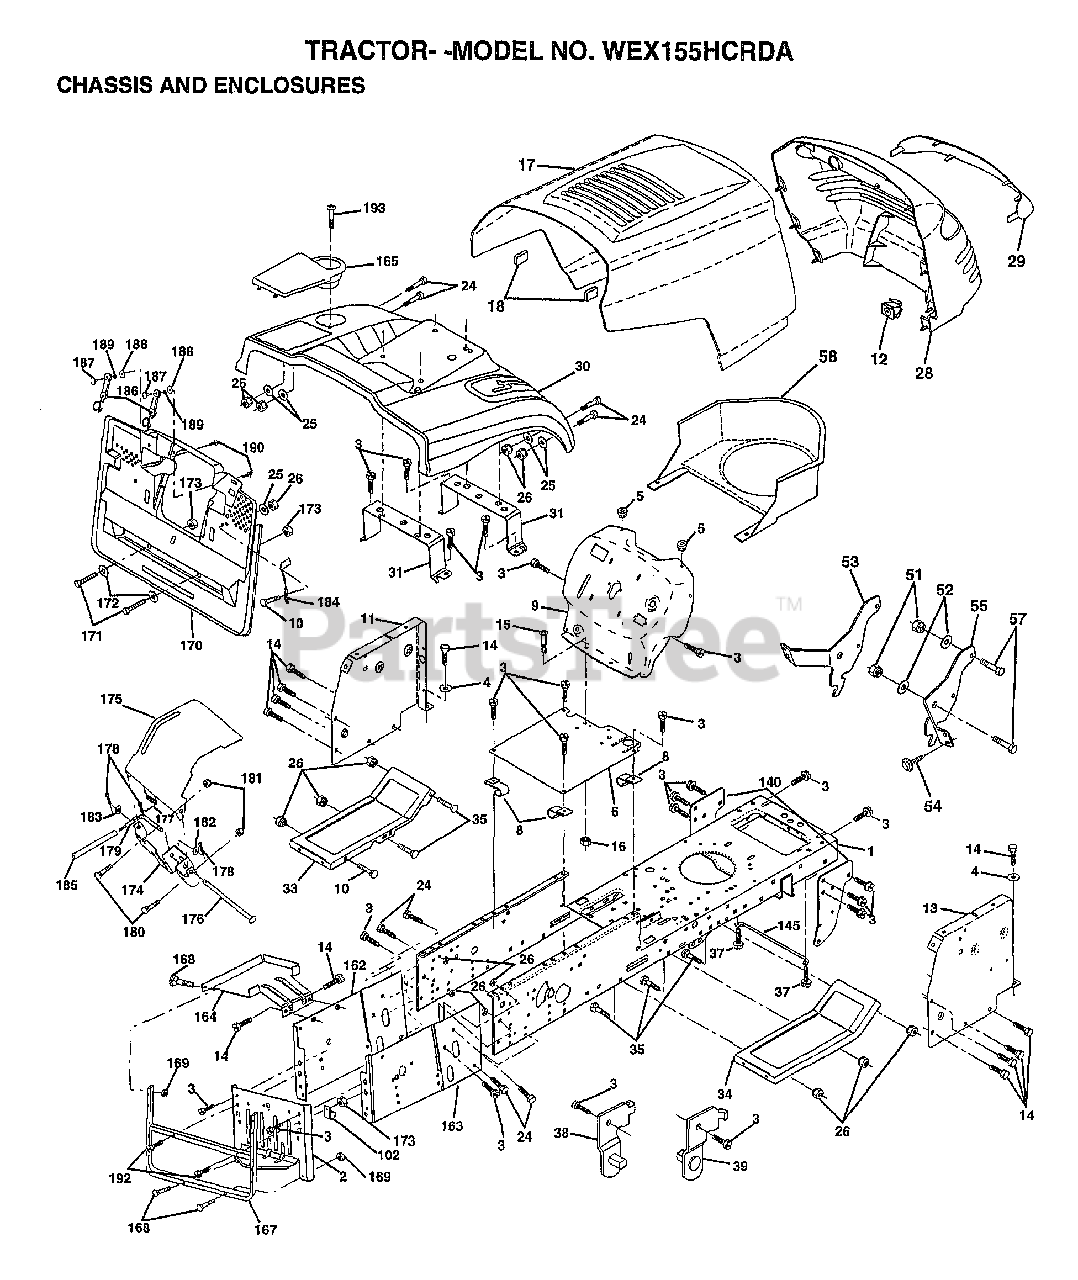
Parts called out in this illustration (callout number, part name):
1	CHASSIS.STAMPING
2	DRAWBAR.CRD
3	SCREW
4	WASHER
5	BUMPER-HOOD/DASH
6	SADDLE
8	"CLIP,INSULATOR"
9	DASH.SILKSCREEN
11	"PANEL-DASH,LH"
12	CLIP.TINNERMAN
14	SCREW LT
15	SCREW
17	HOOD.STEEL.ASSY
24	BOLT
25	WASHER
26	NUT
28	GRILLE-MS428
29	LENS.GRILLE.PRIVATE LABEL
30	FENDER.CRD.GREEN
31	BRKT.SUPT.FENDER.CRD
33	FOOTREST.LH.LT/GT
34	FOOTREST.RH.LT/GT
35	BOLT
37	SCREW LT
38	BRACKET ASM LH
39	BRACKET ASM RH
51	NUT
52	WASHER
53	BRACKET.GRILLE.LH
54	SCREW.HEX.WS.HD
55	BRACKET.GRILLE.RH
58	AIR DUCT
102	CLIP T
140	BRKT SUSPENSION
145	"ROD POVOT,CHASSIS"
148	SCREW
162	BRKT.EXT.CHASSIS.LH.CRD
163	BRKT.EXT.CHASSIS.RH.CRD
164	SUPPORT.BATTERY.CRD
165	COVER.BATTERY.CRD.BLACK.LT
167	SUPT.ASM.BACKPLATE
168	BOLT-RD HD SQ NK
170	COVER.BACKPLATE.BLACK
171	BOLT.HEX.3/8-16X2-1/2
173	NUT
174	BRKT.SWITCH.FBI.CRD
175	GRUARD.DOOR.REAR.CRD
176	HINGE PIN
177	SPRING.COVER.LH
179	ROD.PIVOT.FBI.CRD
182	WASHER.385X.625
183	WASHER
184	BRKT.ACTUATOR.BAG.CRD
185	TUBE.LEVER.SWCH.FBI.CRD
186	LATCH ASSY.BAGGER
187	WELDNUT
188	WASHER #10
189	LOCKWASHER
190	SCREW
192	SCREW LT
193	SCREW LT
